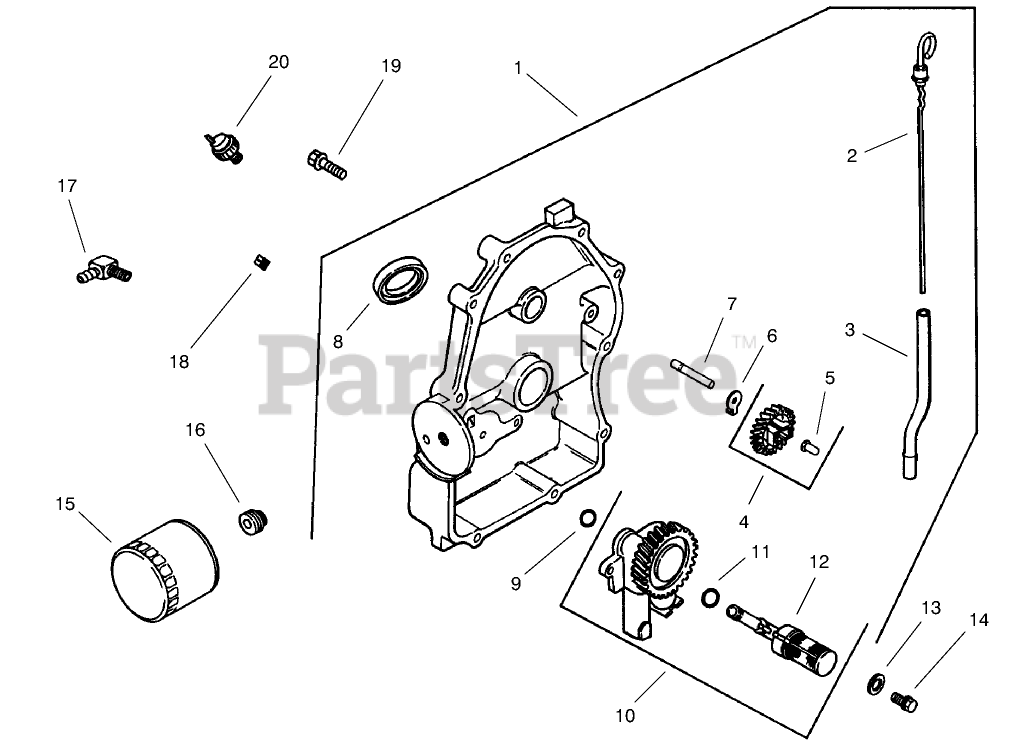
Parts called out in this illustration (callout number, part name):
1	Plate, closure assembly (Includes 2-12)
2	Dipstick
3	Tube-Dipstick
4	Kit-Governor Gear Assembly (Incl. Ref. #7)
5	Pin-Governor
6	Tab-Locking
7	Shaft-Govenor Gear
8	Seal-Oil
9	O Ring
10	Oil pump assembly (Includes 11, 12)
11	ORing
12	Pick Up-Oil
13	Washer
14	Screw
15	Filter-Oil
16	Nipple-Oil Filter
17	Connector
18	Plug
19	Screw
20	Switch-Oil Pressure
